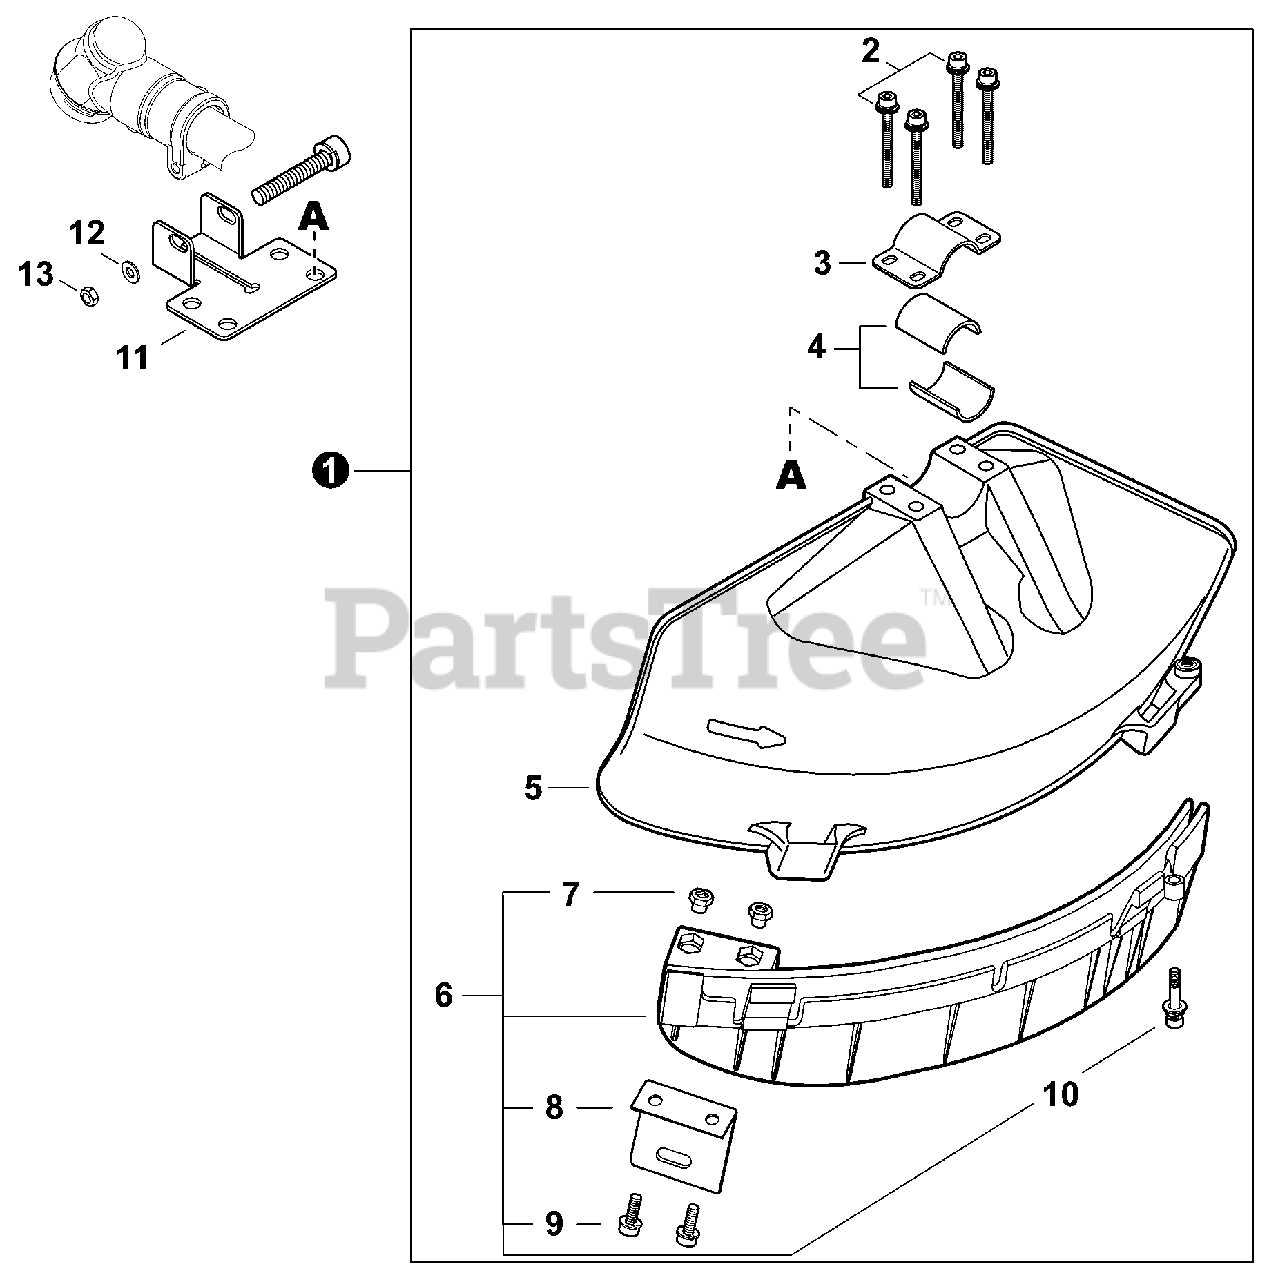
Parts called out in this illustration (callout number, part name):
1	DEBRIS SHIELD KIT
2	BOLT M5×45
3	CLAMP, UPPER
4	SPACER 26
5	SHIELD, DEBRIS - BLADE
6	DEBRIS SHIELD EXTENSION ASSY
9	BOLT 5×16
10	BOLT M5×22
11	PLATE, SHIELD MOUNTING
12	WASHER 6.5×13×1
13	NUT, HEX M6
